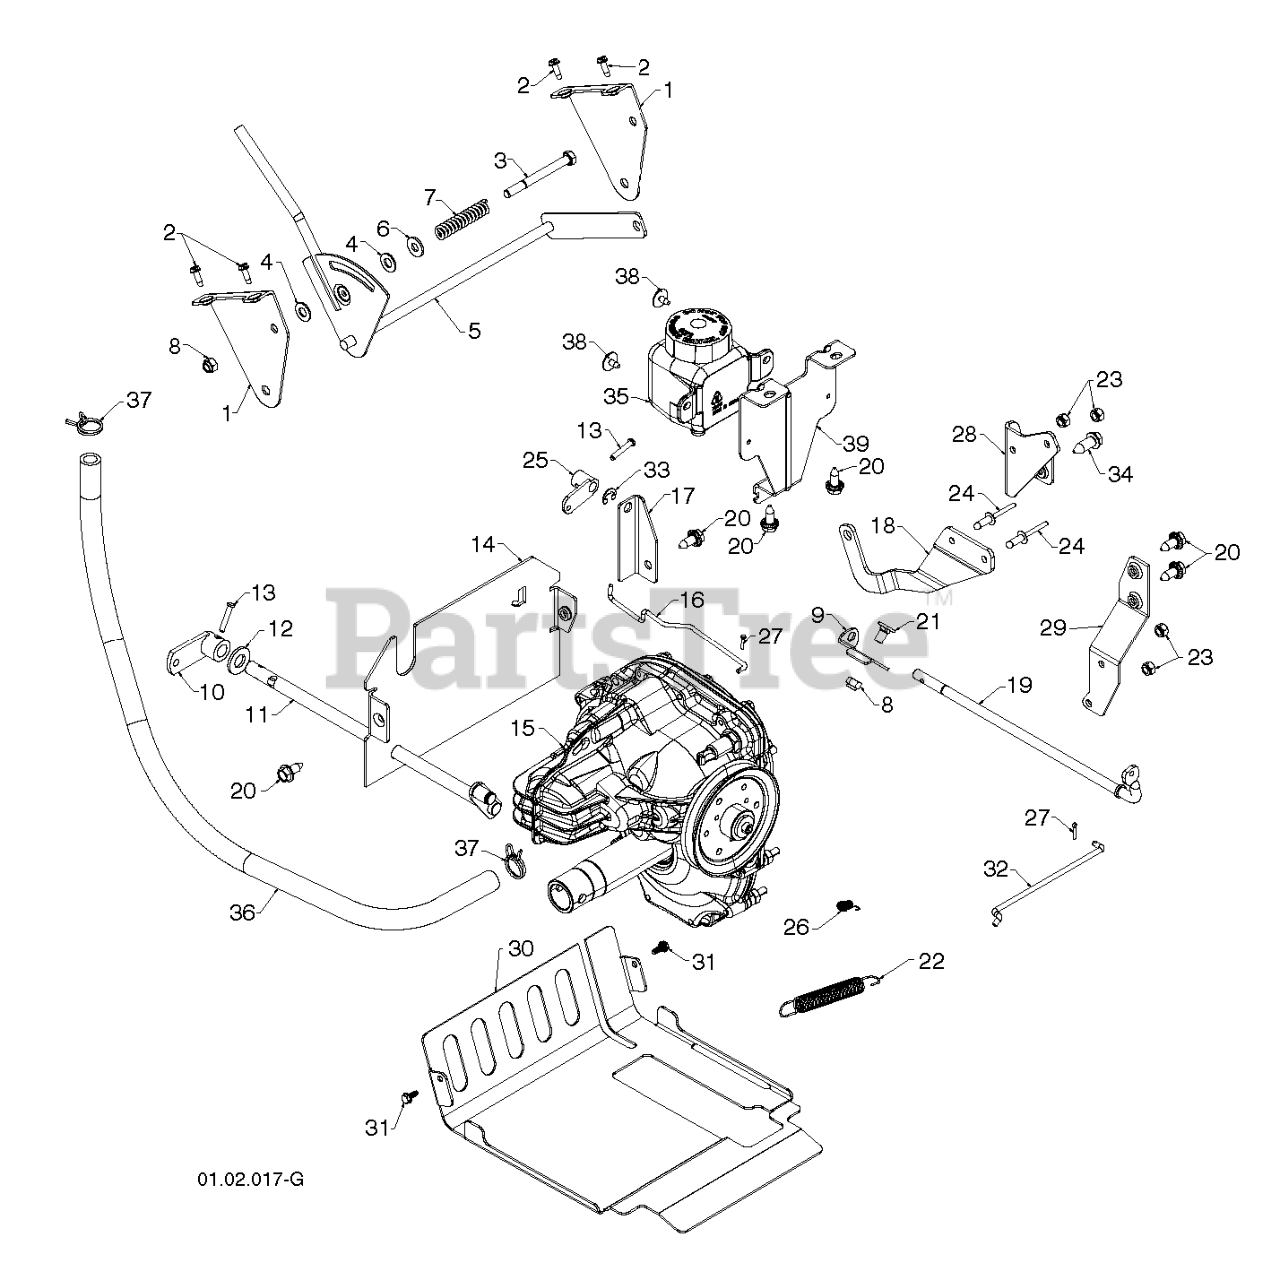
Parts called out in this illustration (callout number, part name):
1	BRACKET.SHIFT.HYDRO
3	SCREW 5/16-18 X 3.25
4	WASHER, NYLON FRICTION
5	LEVER ASSEMBLY, SPEED CONTROL
6	WASHER.20X8.5
7	SRPING.FRICTION.HYDRO
8	NUT.71038.31-18.HEX.NYLOCK
9	BRACKET.HYD.CLUTCH.
10	ARM.CONTRL.PIN.TRACK
11	CONTROL.SHAFT.ASM
12	WASHER.FLAT.1/2
13	CLEVIS PIN
14	PLATE.REAR.HYDRO.TRACK.ORANGE
15	TRANSMISSION 321-0410
16	ROD, BYPASS VALVE
17	BRACKET.HYD.CLUTCH.REAR
18	ARM.CONTROL.HYDRO.SNOW
19	SHAFT.HYD.CLUTCH
20	BOLT.HEX.HD.WASHER.5/16-18X.75
21	BOLT.CARRIAGE.5/16-18X
22	SPRING, BRAKE
23	LOCKNUT.NYLOC.1/4-20
24	RIVET.POP.1/4X.475
25	ARM.HYD.CLUTCH
26	SPRING, TRACTION IDLER
27	RETAINER CLIP
28	BRACKET, ANTI-ROTATE
29	STRAP.TORQUE.HYDRO
30	COVER.TRANSMISSION.TRACK.BLACK
31	SCREW1032X.500
32	ROD.HYDRO CLUTCH
33	E-RING.RETAINER.REINFORCED.375
34	SCREW 5/16-18X1
35	TANK.EXPANSION.350ML 71328
36	HOSE.EXPANSION.TANK.TRACK
37	CLAMP.SPRING.HOSE.795
38	SCREW.HEX.WASH.HD.TAPPING
39	BRACKET.EXPANS.TANK.TRACK.GREY
